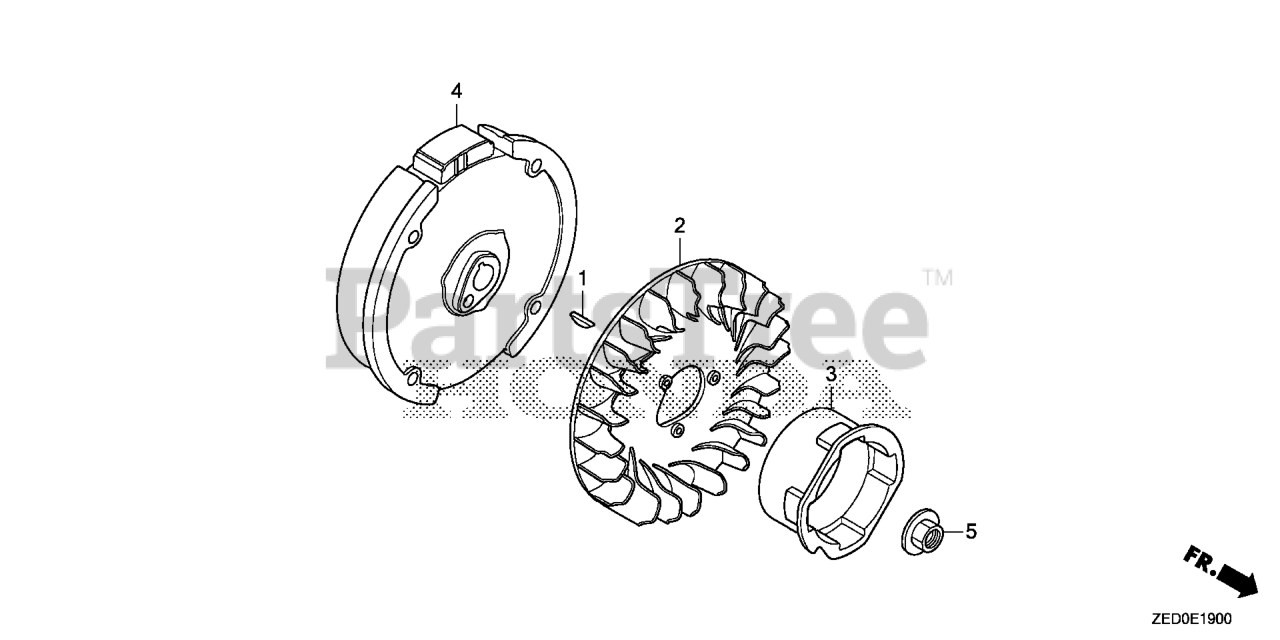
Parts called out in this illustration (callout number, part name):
1	KEY, SPECIAL WOODRUFF (25X18)
2	FAN, COOLING
3	PULLEY, STARTER
4	FLYWHEEL COMP
4	FLYWHEEL (YUXIN)
5	NUT, SPECIAL (14MM)
